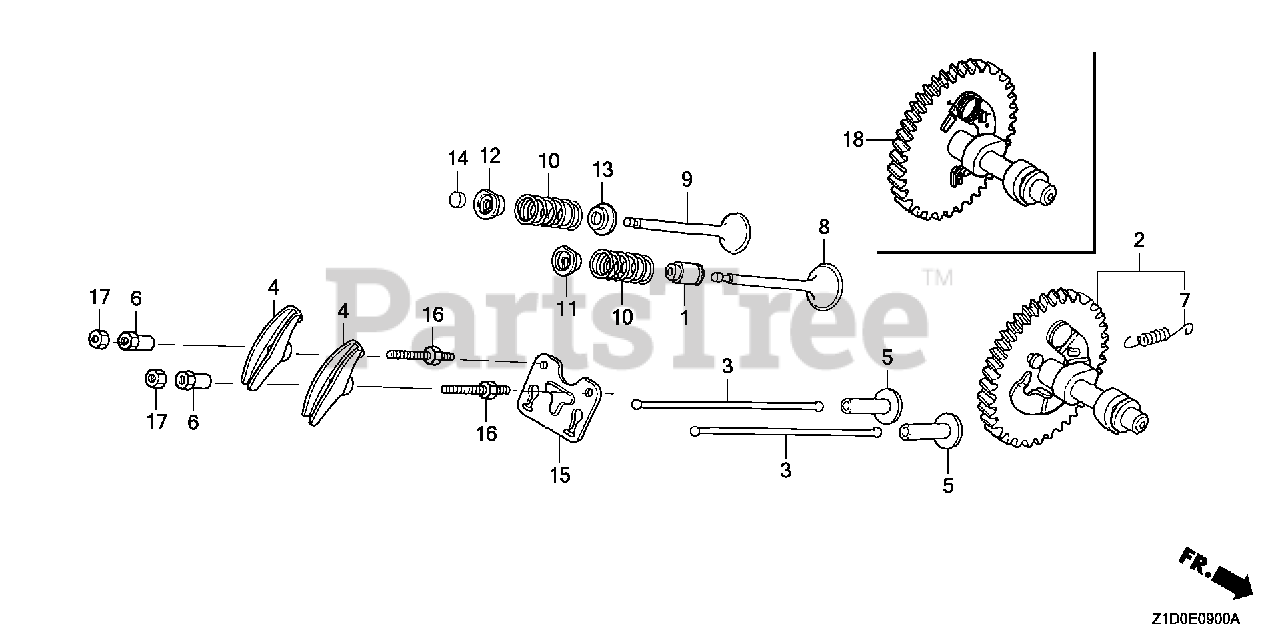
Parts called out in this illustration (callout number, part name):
1	SEAL, VALVE STEM
4	ARM, VALVE ROCKER
5	LIFTER, VALVE
6	PIVOT, ROCKER ARM
8	VALVE, IN.
9	VALVE, EX.
10	SPRING, VALVE
11	RETAINER, IN. VALVE SPRING
12	RETAINER, IN. VALVE SPRING (EXHAUST SIDE)
13	SEAT, VALVE SPRING
15	GUIDE, PUSH ROD
16	BOLT, PIVOT (8MM)
17	NUT, PIVOT ADJUSTING
18	CAMSHAFT ASSY.
